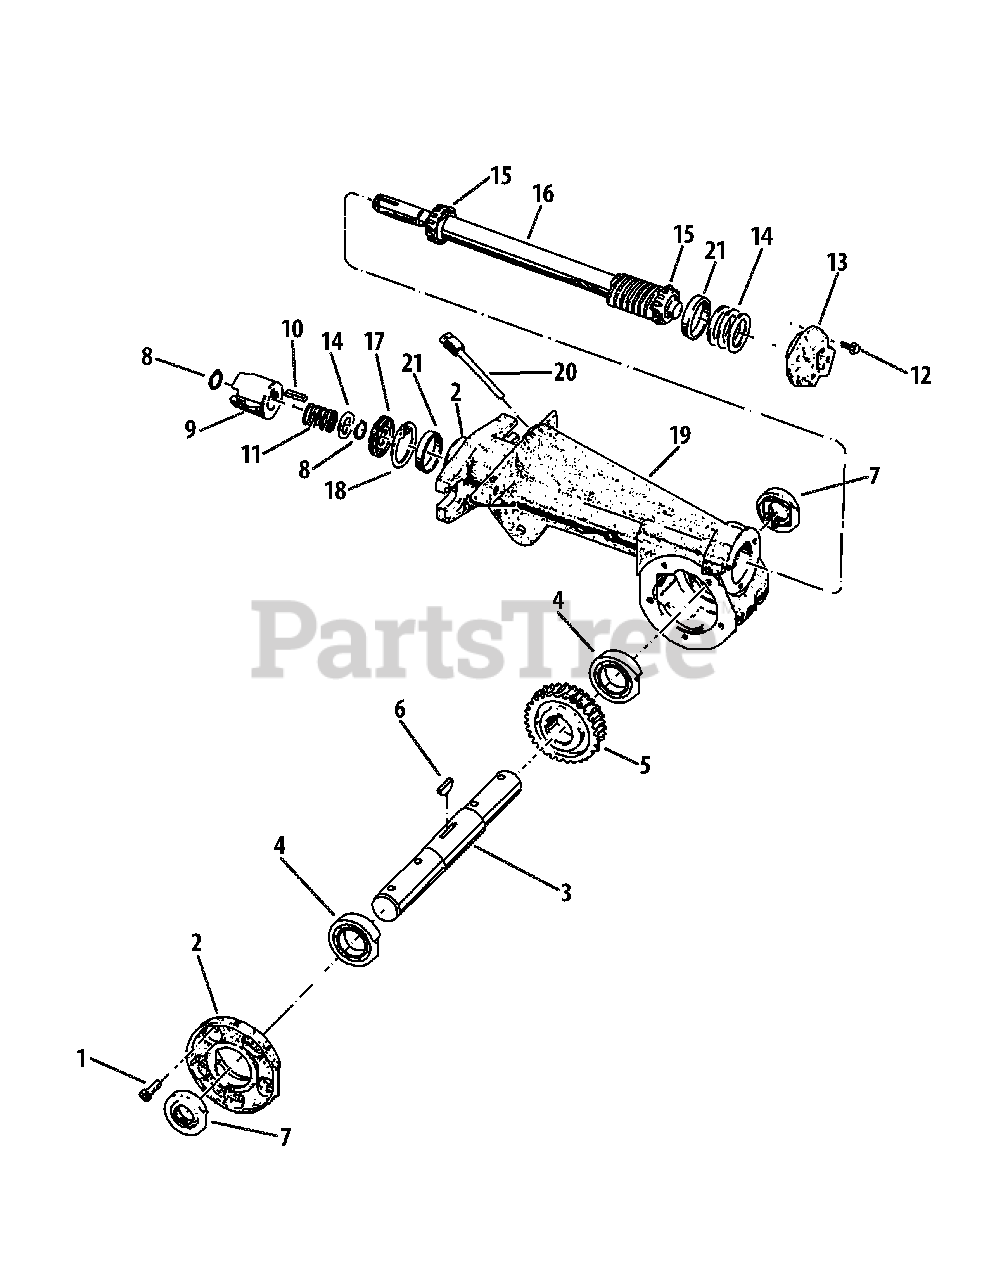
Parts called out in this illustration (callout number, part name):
1	Self-Sealing Screw, 1/4"-20 x 5/8 "
2	Tiller Housing Cover
3	Tine Shaft
4	Ball Bearing
5	Worm Gear
6	Woodruff Key
7	Oil Seal
8	External Retaining Ring
9	Dog Clutch
10	Key, 3/16" x 1"
11	Spring
12	Self-Sealing Screw, 1/4"-20 x 7/8"
13	Cap
14	Flat Washer, 1.75 x 1.5 x .062
15	Cup Bearing
16	Shaft
17	Oil Seal
18	Retaining Ring
19	Attachment Housing
20	Oil Dipstick
21	Cone Bearing
